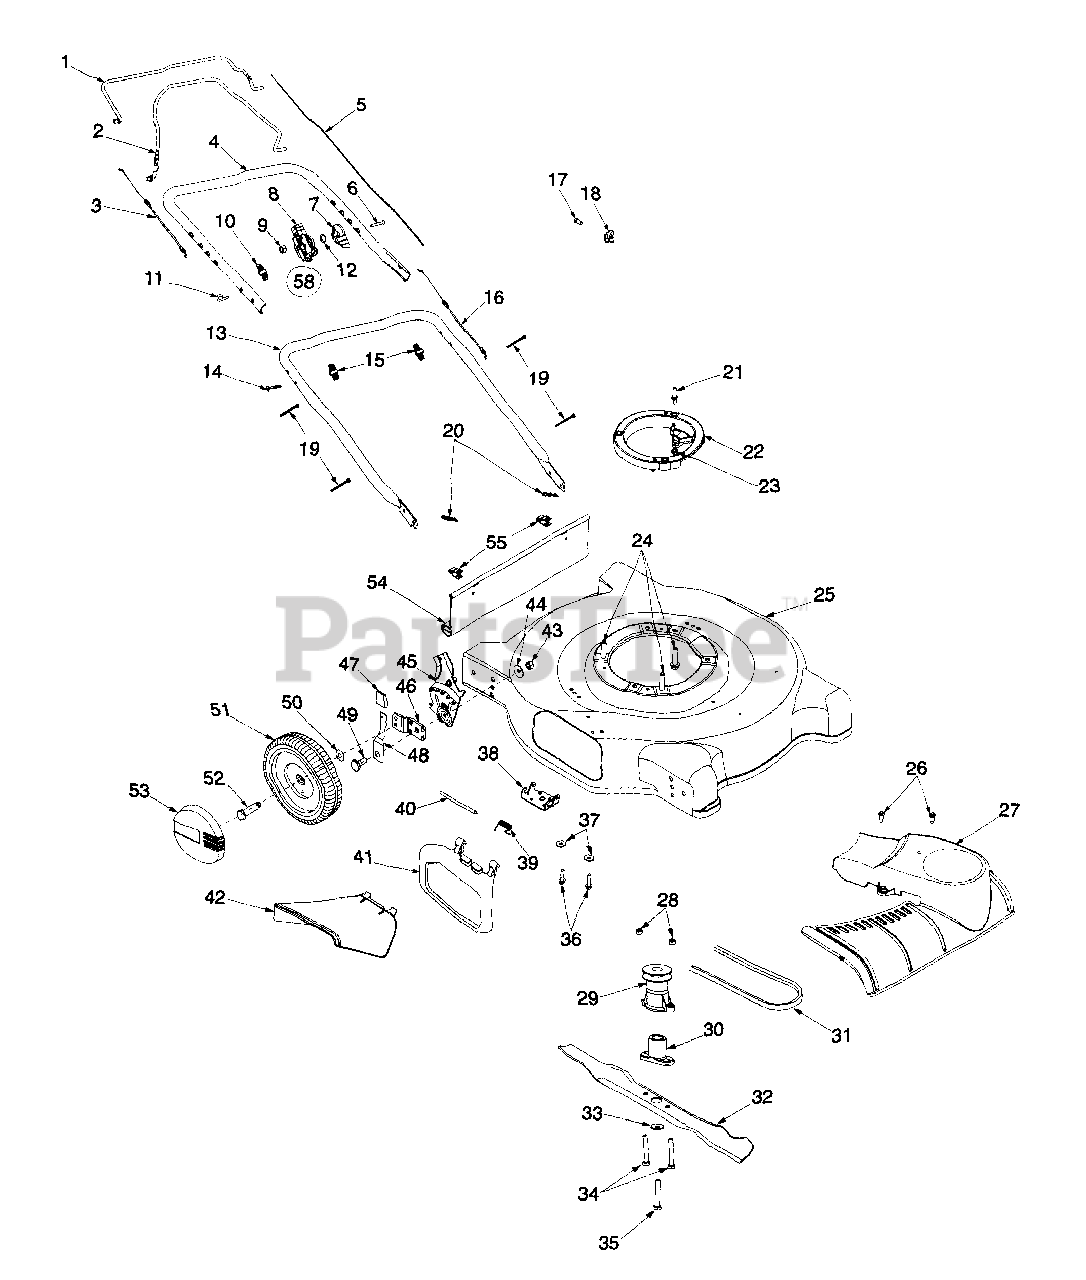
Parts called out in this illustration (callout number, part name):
6	Screw Oval C-Sunk 1/4-20 x 1.81
7	Throttle Lever
8	Throttle Housing
9	Hex Lock Nut 1/4-20
11	Eye Bolt 1/4-20
12	Curved Washer .663 x .980 x .014
14	Carriage Bolt 5/16-18 x 2.0
15	Knob
16	Throttle Cable: 51"
17	Hex Screw: T: #10-32 x .625
18	Cable Clamp
19	Tie Cable
20	Cotter Pin
21	Pin-Belt Keeper
22	Engine Spacer
23	Hex Nut 1/4-20 Thread
24	Tapp Screw w/Hex Lock Wash
27	Trans Cover - Black w/Logo
28	Hex Lock Nut 1/4-20 Thd.
29	Drive Pulley
30	Blade Adapter Kit
31	V-Belt
32	Blade 22"
33	Bell Washer .396 I.D. x 1.140 O.D. x .095
34	Hex Screw 1/4-20 x 1.50
35	Hex Screw 3/8-24 x 2.50
36	Tapp Screw 1/4-20 x .500
37	Bell Wash .265 x .75 x .062
39	Torsion Spring
40	Hinge Pin
41	Mulch Plug
42	Chute Deflector
43	Hex Nut 3/8-16
44	Bell Washer .39 ID x 1.38 OD
47	Knob
48	Height Lever
49	Shldr Screw .500 Dia x .434
50	Bell Washer .380 x .880 x .062
51	Wheel 8 x 1.75 Disk Bar Gray
52	Shoulder Screw .498 x 1.445
53	Hubcap: Euro: Grey
54	Rear Flap
55	Clip
58	Throttle Comp.
